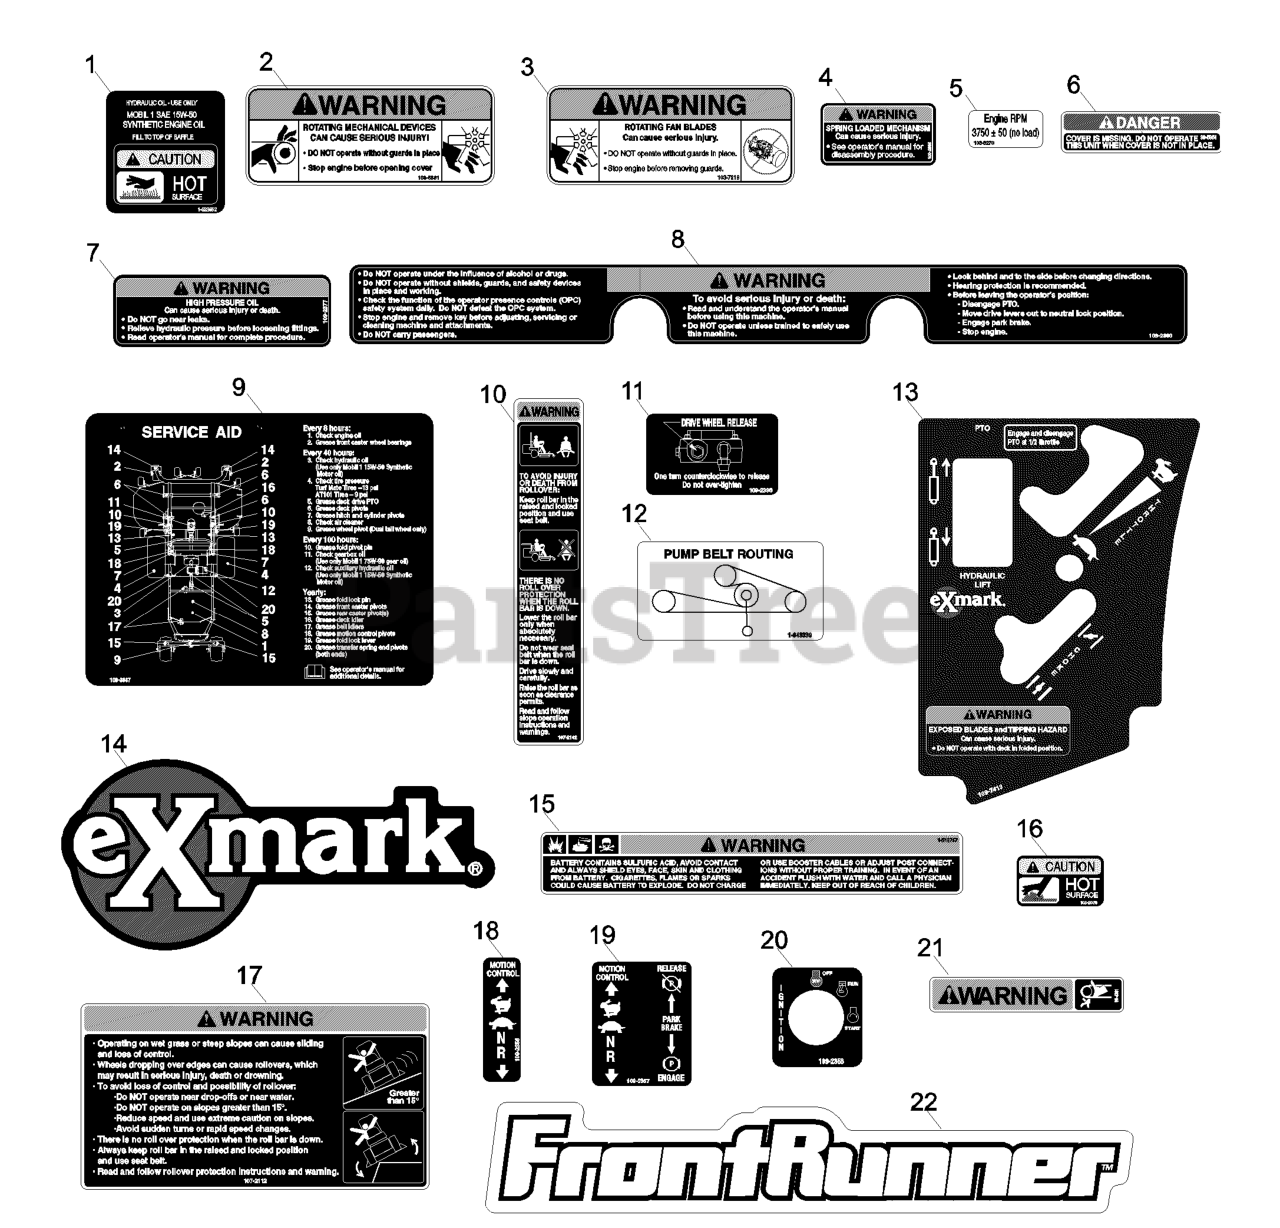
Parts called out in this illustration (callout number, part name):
2	DECAL-DEVICES, ROTATING
3	DECAL,PUMP FAN WARNING
4	DECAL,SPRING LOADED
6	DECAL-COVER, MISSING
7	DECAL,HIGH PRESSURE OIL
8	DECAL,TOP CONSOLE
9	DECAL,FR SERVICE AID
10	DECAL-WARNING, FOLDING RO
11	DECAL,PUMP DRIVE RELEASE
12	DECAL-ROUTING, BELT
13	DECAL,CONTROL FMZ A/C
14	DECAL,EXMARK LOGO
15	DECAL-BATTERY
16	DECAL-CAUTION
17	DECAL-WARNING
18	DECAL-CONTROL, MOTION
19	DECAL,MOTION CNTL/PARK BR
20	DECAL,IGNITION
21	DECAL-WARNING
22	DECAL,FRONTRUNNER
